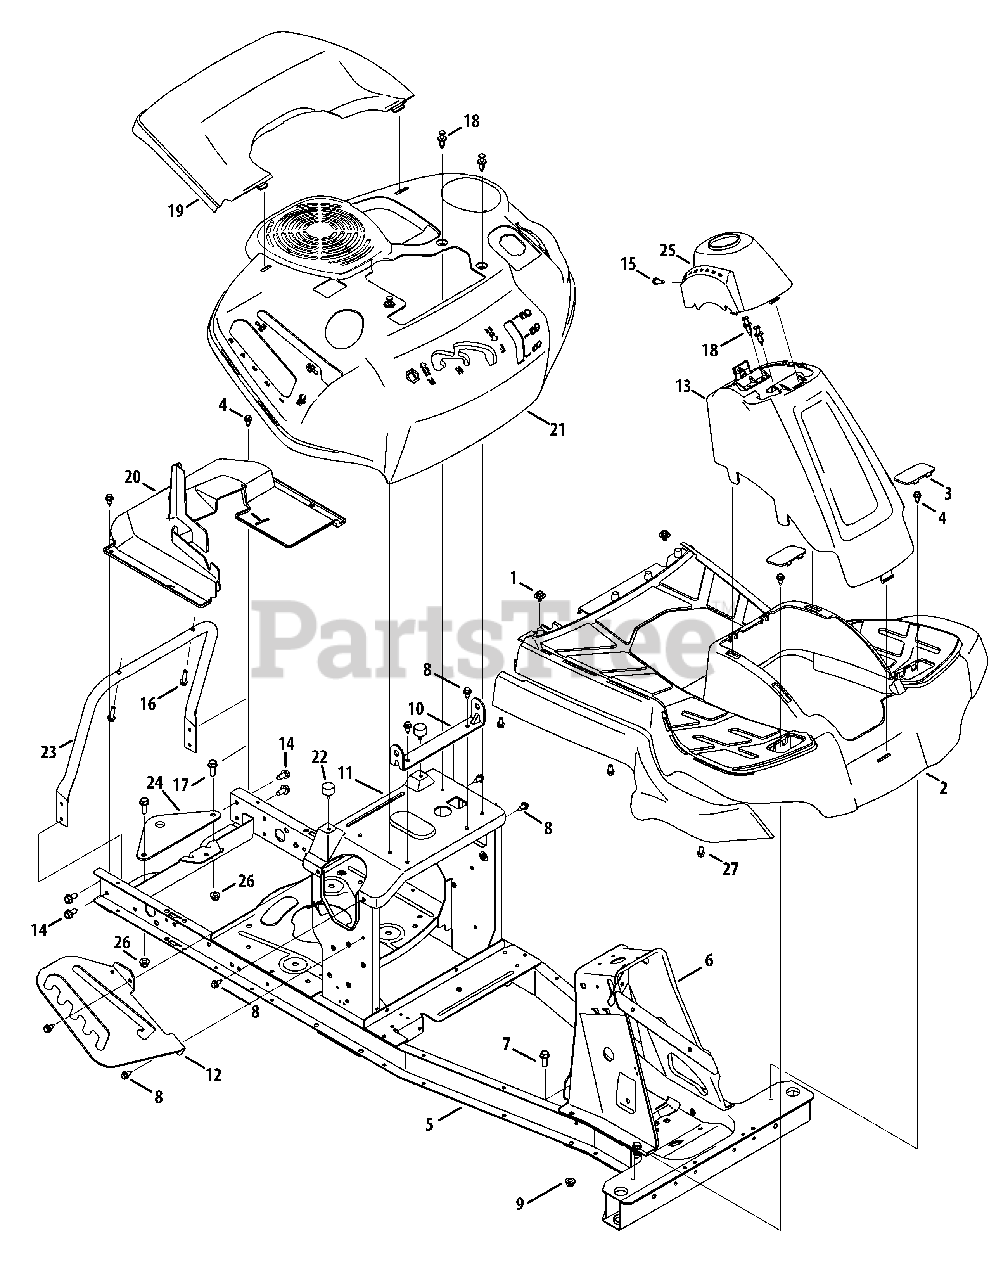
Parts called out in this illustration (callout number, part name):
1	Screw, 1/4-20 x .500
2	Running Board, RMC
3	Running Board Plug
4	Shoulder Screw, .368 X.113: 1/4-20
5	Frame Assembly
6	Column Assembly
7	Hex Washer Screw, 5/16-18 x .75
8	Tap Screw, 1/4-20, .625
9	Flange Locknut, 5/16-18
10	Seat Pivot Bracket
12	Deck Lift Index Bracket
13	Column Cover (Orange)
14	Tap Screw, 5/16-18, .750
15	Machine Screw, 1/4-20, 0.750
16	Hex Screw, 1/4-15, 1.0
17	Hex Head Screw, 5/16-18, .75
18	Rivet, .3125
19	Rear Cover (Orange)
20	Top Rear Drive Cover
21	Fender, (Orange)
22	Bumper, .62 Dia. x .50
23	Rear Cover Support Tube
24	Hitch Plate
25	Steering Column Cap (Orange)
26	Flange Lock Nut 5/16-18 Gr. F
27	Screw 1/4-15 x 0.50
